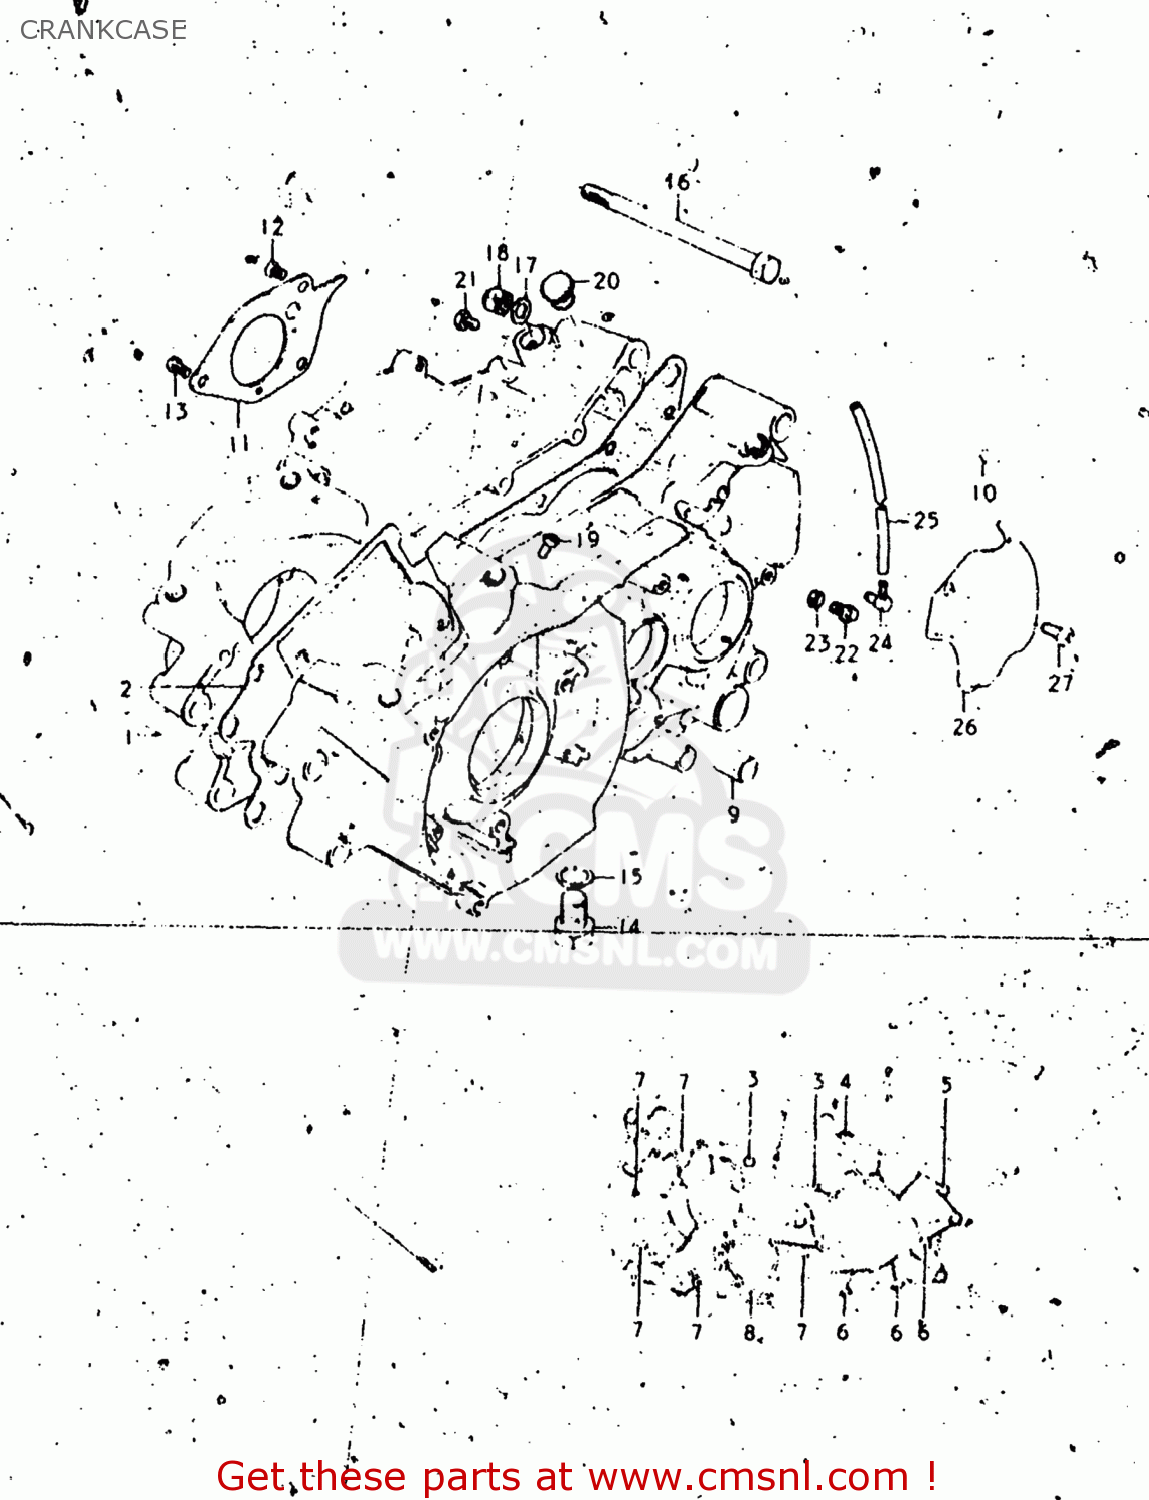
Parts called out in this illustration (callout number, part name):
1	CRANKCASE SET
2	GASKET,CRANKCASE (MCA)
3	SCREW
4	SCREW 6X70
5	SCREW
6	SCREW
7	SCREW (6X45)
8	SCREW (6X35)
9	PIN
10	CAP
11	PLATE,OIL RESERVOIR
12	SCREW
13	SCREW
14	PLUG
15	GASKET(14X19.2X2) (NAS)
16	BOLT 10X120
17	WASHER
18	NUT
19	SCREW,6X6
20	Plug
21	BOLT(6X6)
22	BOLT
23	GASKET 6.2X12X1.5 (MCA)
24	UNION,OIL HOSE
25	HOSE
26	CAP,OIL PUMP INSPECTION
27	SCREW
